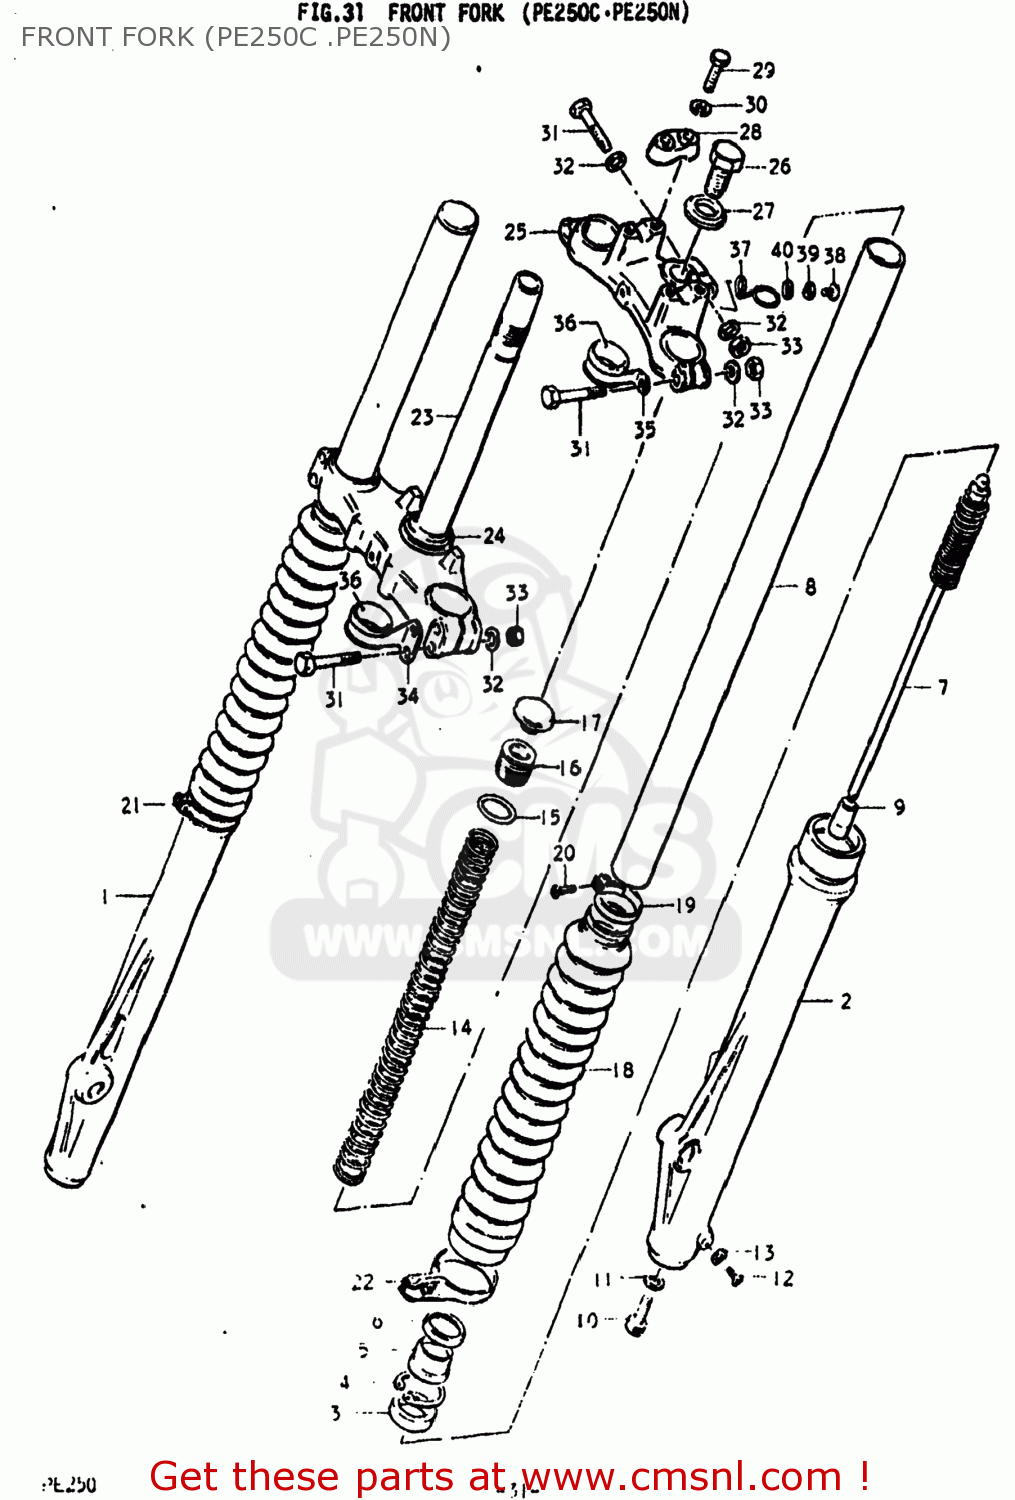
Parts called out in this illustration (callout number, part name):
0	DAMPER SET
1	TUBE,OUTER,RIGHT
2	TUBE,OUTER,LEFT
3	OIL SEAL,FRONT FORK
4	CIRCLIP,FORK OIL SEAL
5	DUST SEAL,FRONT FORK
6	GUIDE.FORK DUST
7	CYLINDER,FRONT FORK
8	TUBE,FORK,INNER
9	PIECE,OIL LOCK
10	BOLT,FORK CYLINDER(10X25)
11	GASKET (NAS)
12	SCREW
13	GASKET,DRAIN,PLUG (NAS)
14	SPRING
15	O RING
16	CAP,FORK INNER TUBE
17	CAP,FRONT FORK
18	BOOT
19	BAND,BOOT
20	SCREW
21	BAND,FRONT FORK COVER
22	BAND,FRONT FORK COVER
23	STEM,STEERING
24	RACE,STEERING OUTER LWR
25	HEAD,STEERING STEM
26	BOLT,STEERING STEM HEAD
27	WASHER
28	HOLDER,HANDLEBAR
29	BOLT
30	LOCK WASHER
31	BOLT 8X55
32	WASHER
33	NUT
34	GUIDE,CABLE
35	GUIDE,CABLE
36	SLEEVE
37	CLIP,CABLE
38	SCREW 6X12
39	LOCK WASHER
40	WASHER
